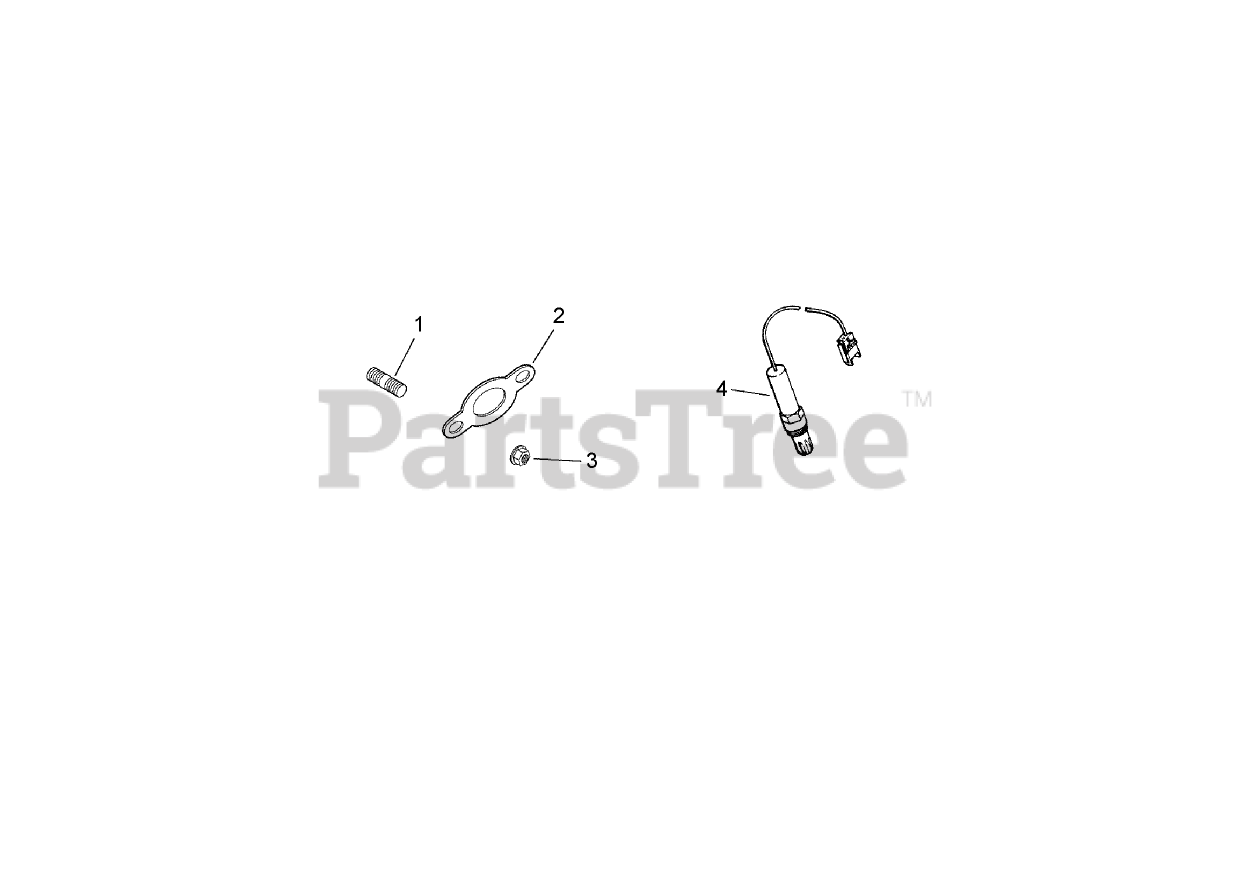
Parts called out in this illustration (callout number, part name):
1	STUD (M8X1.25X33)
2	GASKET-EXHAUST
3	NUT-FLANGE (M8X1.25)
4	Sensor-Oxygen
